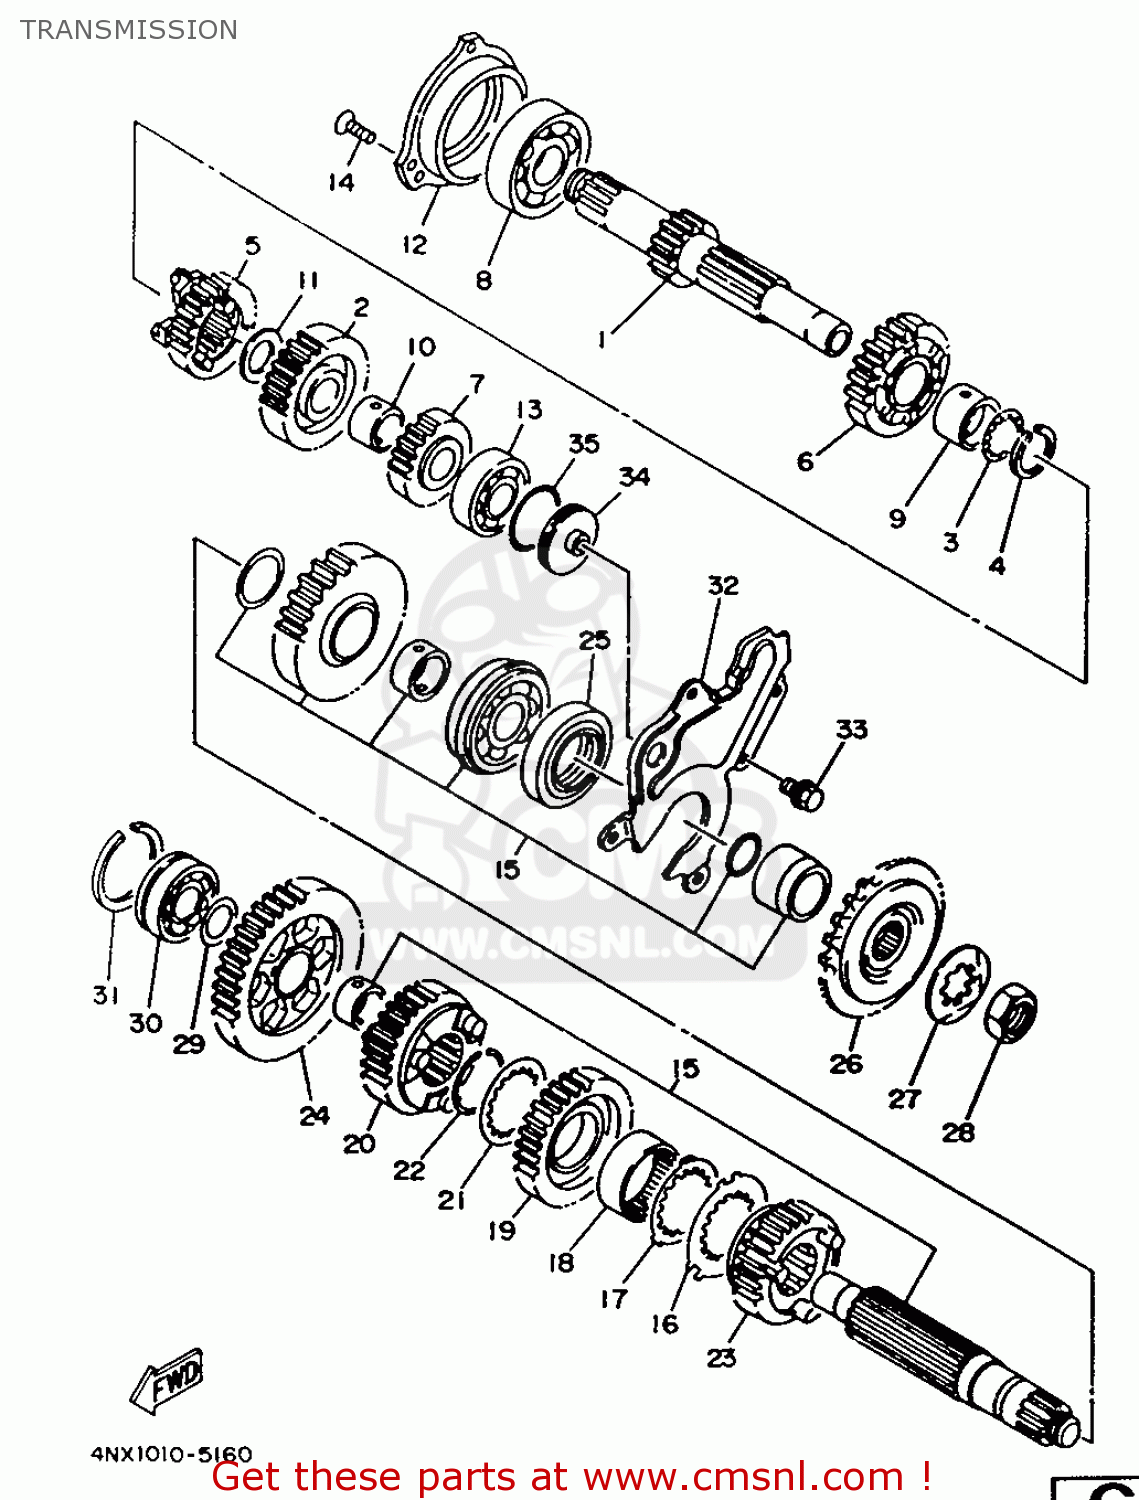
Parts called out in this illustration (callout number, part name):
01	AXLE, MAIN (13T)
02	GEAR, 5TH PINION
03	WASHER(3VD)
04	CIRCLIP (4L0)
05	GEAR, 3RD PINION(21T)
06	GEAR, 4TH PINION
07	GEAR, 2ND PINION
08	BEARING (3Y1)
09	COLLAR(1FN)
10	COLLAR(1FN)
11	WASHER, PLATE(1FN)
12	HOUSING, BEARING 1
13	BEARING(3LD)
14	SCREW(3LD)
15	DRIVE AXLE ASSY
16	WASHER(3VD)
17	WASHER(3VD)
18	COLLAR(3VD)
19	GEAR, 3RD WHEEL(30T)
20	GEAR, 4TH WHEEL
21	WASHER(3VD)
22	CIRCLIP(3VD)
23	GEAR, 5TH WHEEL
24	GEAR, 1ST WHEEL
25	OIL SEAL(4NX)
26	SPROCKET, DRIVE
27	WASHER, LOCK(3LD)
28	NUT(3LD)
29	WASHER PLATE 168171160000
30	BEARING(1FN)
31	CIRCLIP(1FN)
32	PLATE, COVER
33	BOLT, FLANGE
34	COVER, AIR CLEANER
35	O-RING (626)
